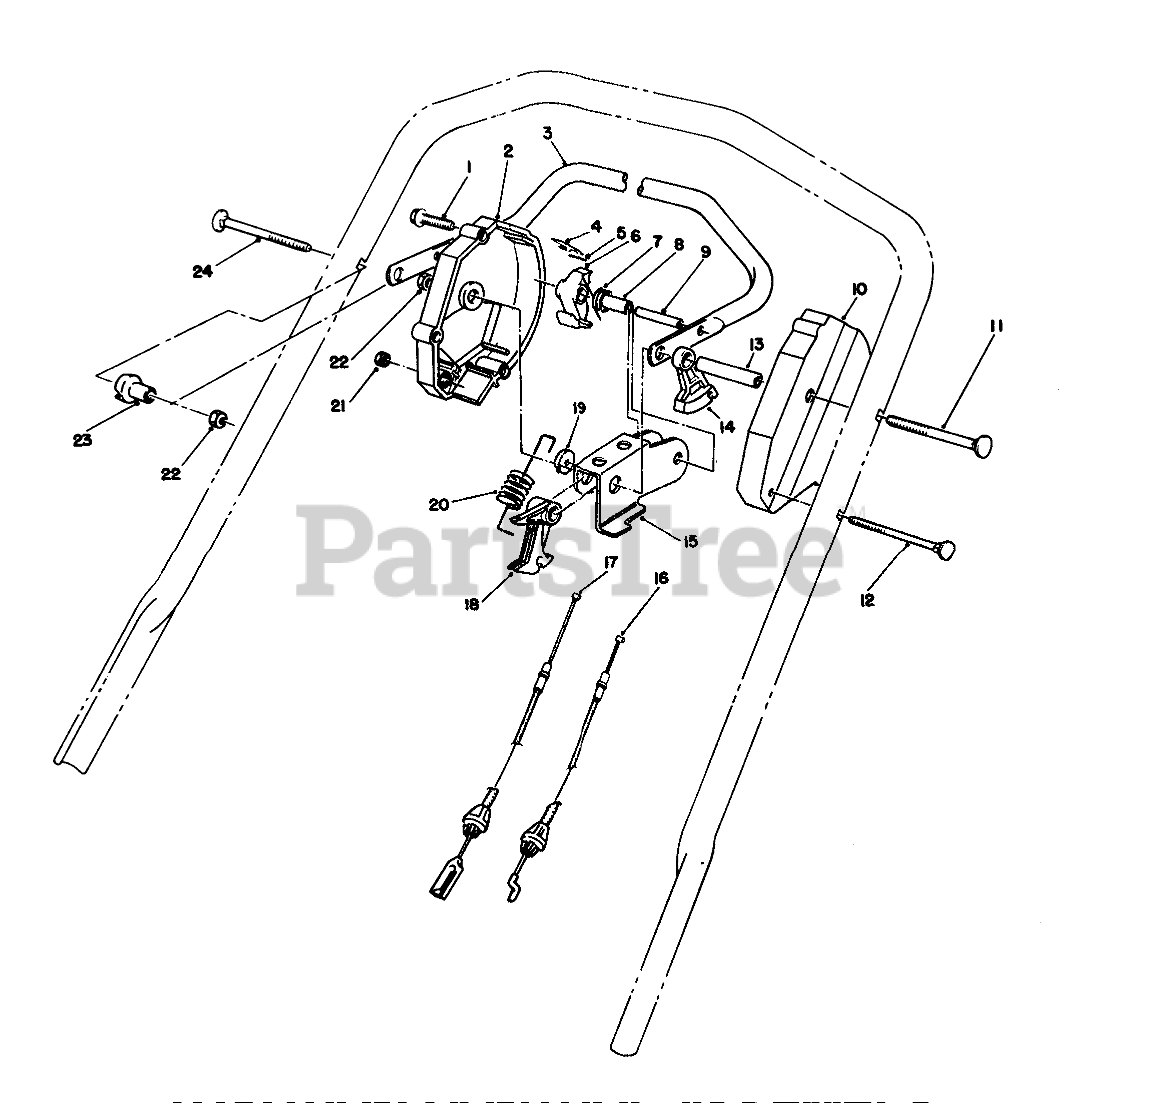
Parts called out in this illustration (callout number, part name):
1	SCREW-HWHTF
2	Housing-Control
3	Bar-Control
4	SPRING-LEAF
5	PIN-INSERT
6	HOOK-CONTROL
7	SPRING-TORSION
8	SPACER
9	PIN-ROLL, SLOTTED
10	HOUSING-CONTROL, LH
11	Screw-Handle
12	HANDLE SCREW
13	TUBING-SPACER
14	LEVER-TRACTION
15	ROCKER
16	Cable-Traction
17	Cable-BBC
18	LEVER-CABLE
19	WASHER-NYLON
20	SPRING-DETENT
21	NUT-HEX
22	NUT-LOCK, NI
23	SPACER-SUPPORT
24	SCREW-HANDLE
